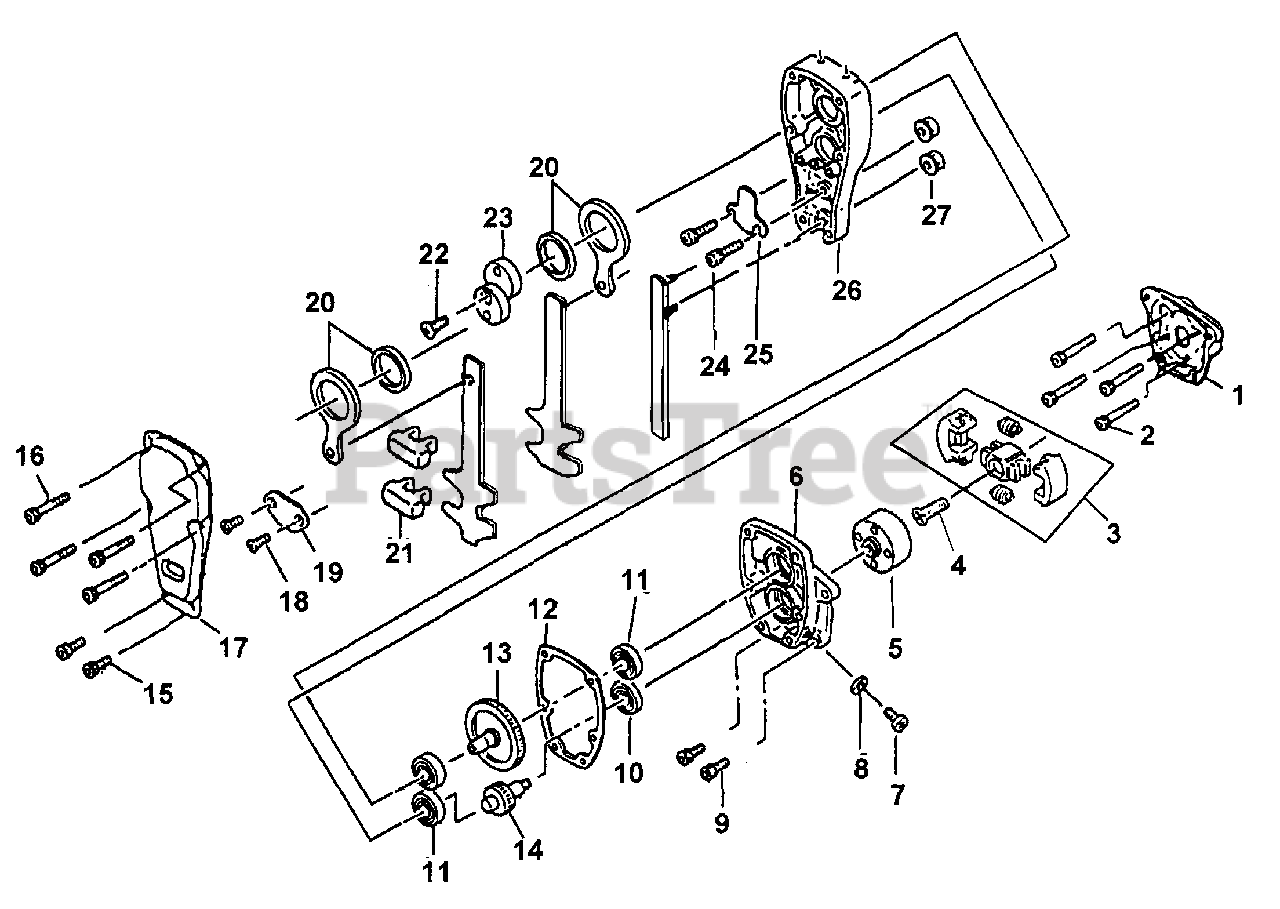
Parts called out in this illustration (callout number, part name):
1	ENGINE BASE
2	SOCKET SCREW
3	CLUTCH ASSY.
4	FLAT SCREW
5	CLUTCH DRUM
6	GEAR CASE
7	SCREW (M6 X 10)
8	WASHER, FLAT
9	SOCKET SCREW
15	SOCKET SCREW (M5 X 10)
16	SOCKET SCREW (M X 40)
17	CAM CASE COVER
18	FLAT SCREW (M5 X 10)
19	FIXING PLATE
21	FELT PACKING
22	CAM PUSH SCREW
24	HEX BOLT (M5 X 30)
25	SLIDE PLATE
26	CAM CASE
27	FLANGE NUT (M6)
